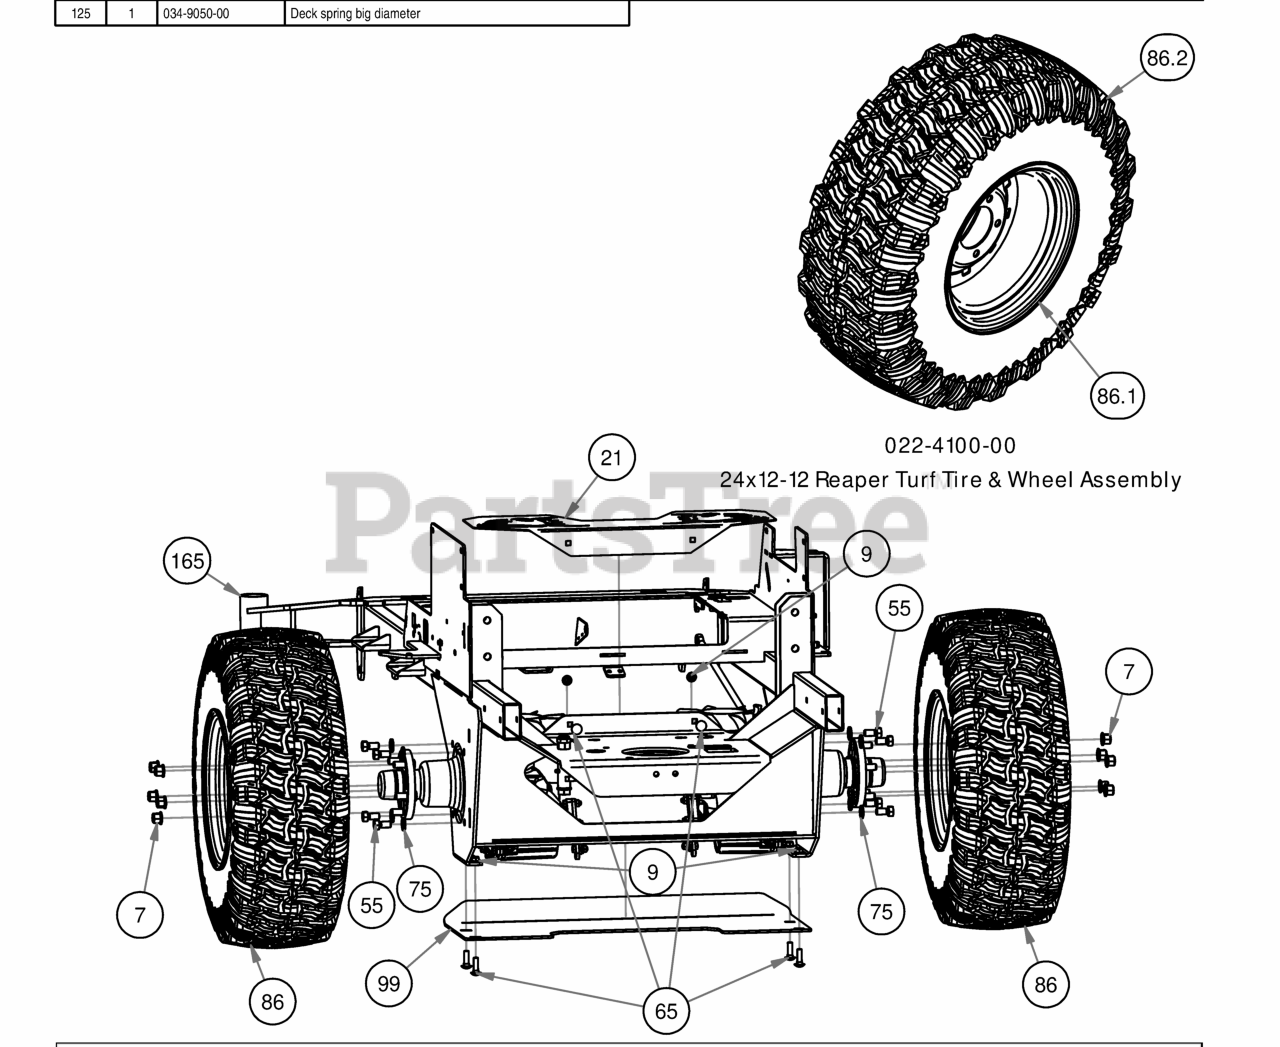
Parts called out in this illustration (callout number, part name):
7	Acorn Lug Nut
9	3/8" Nylock Flange Nut
21	2019 Rigid Fan Guard
55	1/2" x 1" Hex Bolt
65	3/8" x 1 1/4" Carriage Bolt
75	1/2" Lock Washer Zinc
86	24x12-12 Reaper Turf Tire & Wheel Assembly
86.1	12x12" Black Wheel For 2015 Outlaw
86.2	24x12-12 Reaper Turf Tire
99	2019 Outlaw Rigid Skid Plate
165	2019 Rigid Frame
